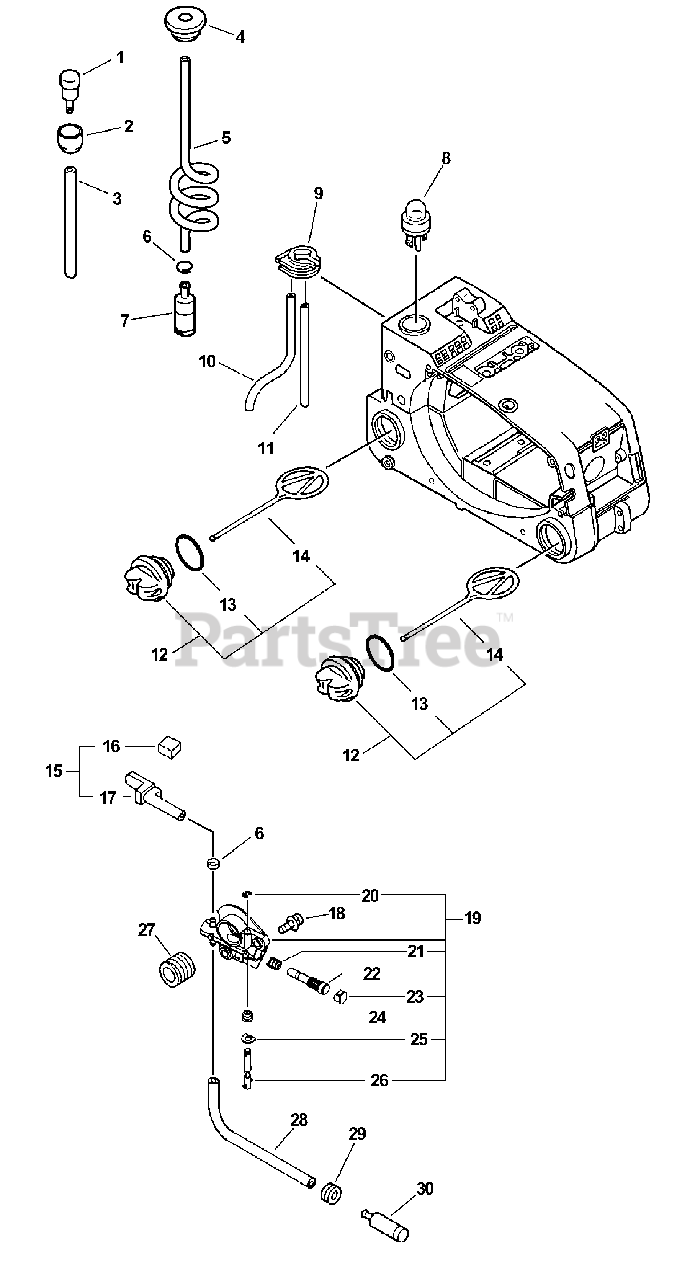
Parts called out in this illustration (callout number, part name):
1	VENT ASSY
2	HOLDER, VENT
3	PIPE, FUEL 3×5×150 BLACK
4	GROMMET, FUEL
5	PIPE, FUEL 3×6×160
6	CLIP Ø6.5 MM
7	FILTER, FUEL
8	BULB, PURGE
9	BRACKET, BULB
10	PIPE, FUEL 2×4×42 CLEAR
11	PIPE, FUEL 3x-5x-70 BLACK
12	CAP ASSY, OIL
13	O-RING 25
14	CONNECTOR, CAP L= 60 MM
15	PIPE KIT, OIL
16	PAD, FOAM
17	PIPE, OIL OUTLET
18	SCREW 5×12
19	AUTO-OILER ASSY
22	PLUNGER ASSY
23	CAP, OIL PUMP
26	ADJUSTER, OILER
27	GEAR, WORM
28	PIPE 3×6×115 BLACK
29	GROMMET
30	FILTER, OIL
